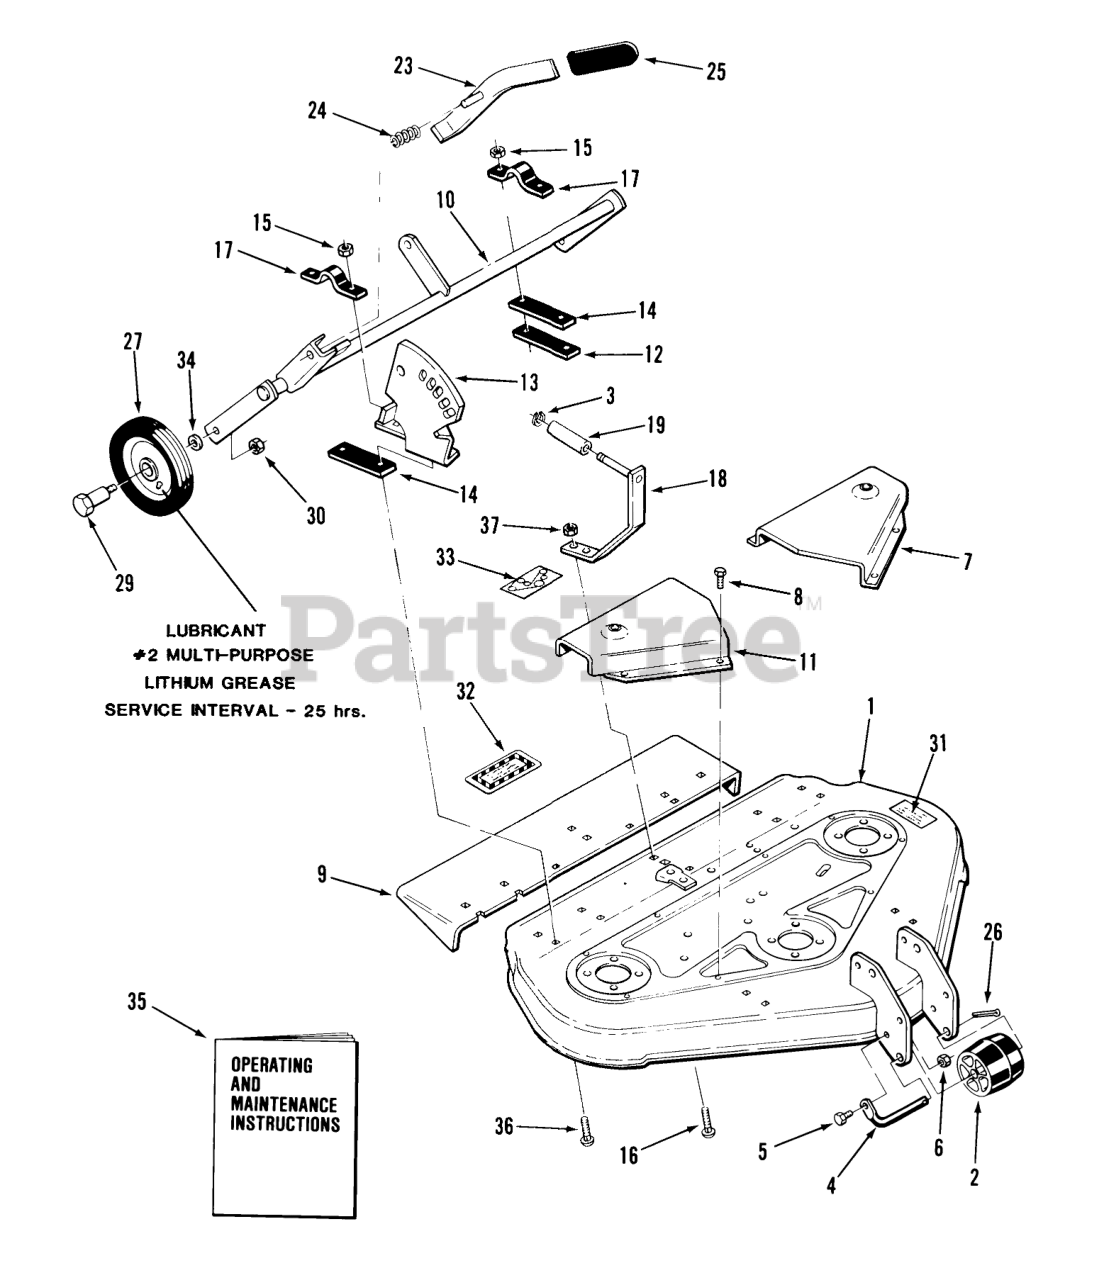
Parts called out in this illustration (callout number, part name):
1	ASSY-MOWER DECK 3 R
2	Roller
3	Snap Ring
4	ROLLER-SHAFT
5	H H C S
6	Nut
7	Cover-Belt
8	SCREW -4
9	Chute Extension
10	ASSY GAGE WHEEL S R
11	Belt Cover RH
12	Bar
13	Quadrant
14	STRAP 1/16 B
15	Nut
16	Bolt
18	BRACKET ASSY R
19	SPACER
23	Lever
24	SPRING-COMPRESSION
26	Cotter Pin
27	WHEEL
29	BOLT-SHOULDER
30	Nut
31	Caution Decal
32	Decal-Caution
33	DECAL-HEIGHT BELT
34	WASHER
35	Operating & Maintenance Instructions
36	Bolt-Carriage
37	NUT
